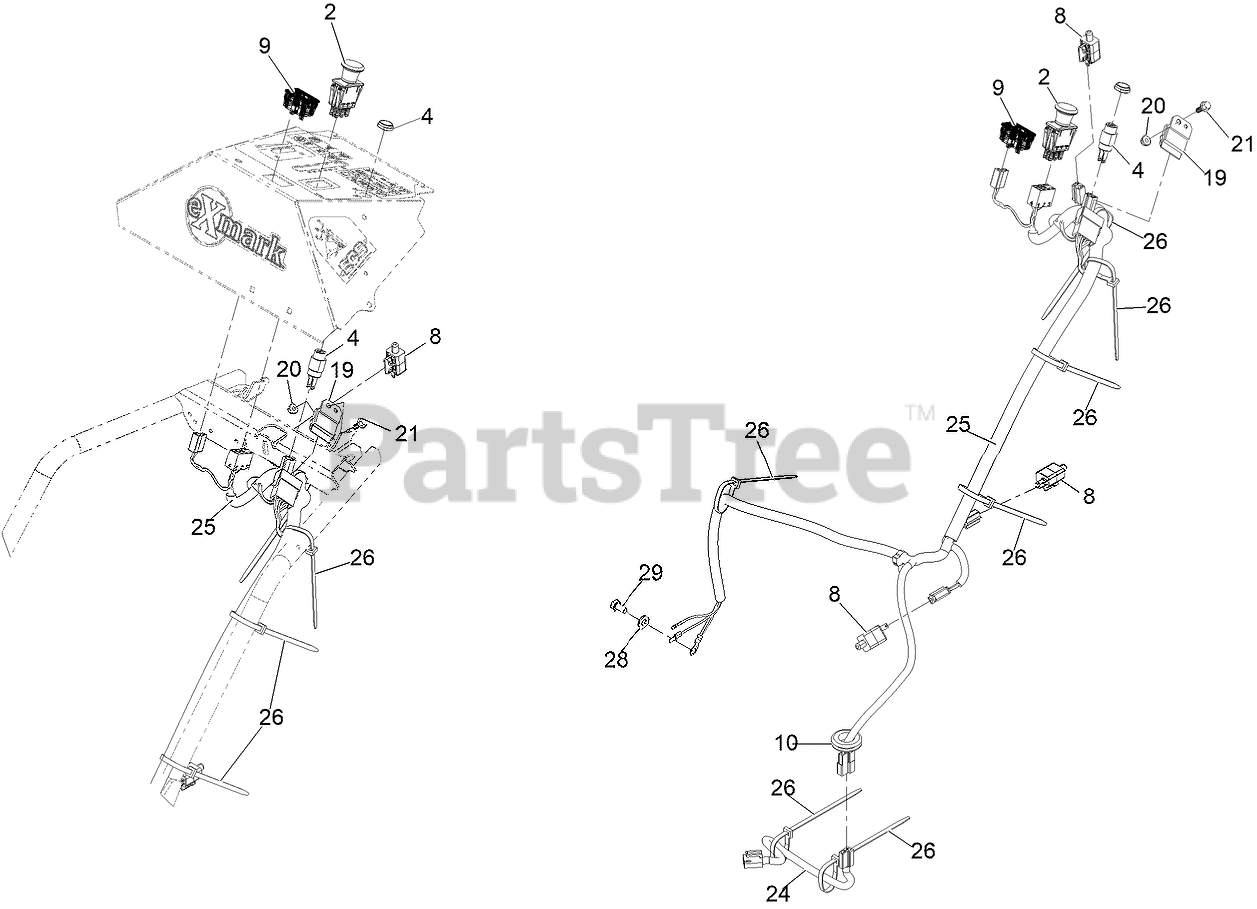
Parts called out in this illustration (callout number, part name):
2	SWITCH-PTO
4	SWITCH & KEY (INCLUDES NU
4	NUT-SWITCH, IGNITION
9	METER-HOUR
10	GROMMET
19	MODULE-INTERLOCK
21	SCREW-HHF
24	HARNESS-CLUTCH PIGTAIL
25	HARNESS-MAIN
26	TIE-CABLE
28	WASHER-PLAIN
29	SCREW-HH
